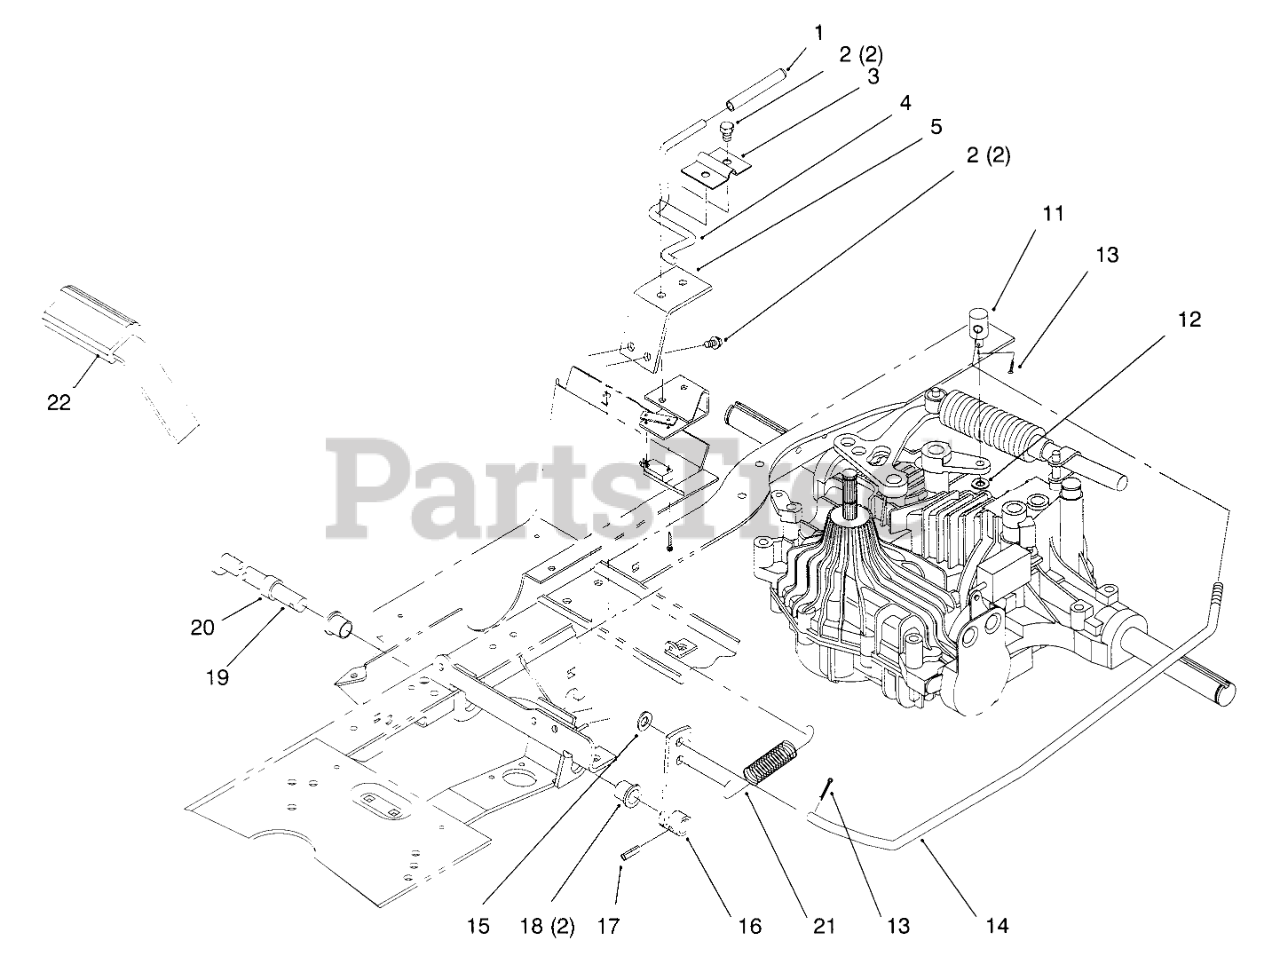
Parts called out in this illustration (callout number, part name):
1	GRIP - PARKING BRAKE
2	SCREW-HWHTF
3	BRKT-PARKING BRAKE
4	ROD - PARKING BRAKE
5	SUPPORT - P. BRAKE
11	TRUNNION - BRAKE
12	WASHER-PLAIN
13	PIN-COTTER
14	ROD - BRAKE
15	WASHER-FLAT
16	Lever-Brake
17	PIN-SPRING
18	BUSHING-FLANGE
19	Pedal-Brake
20	SPACER-BRAKE
21	SPRING-EXTENSION
22	PAD-PEDAL
